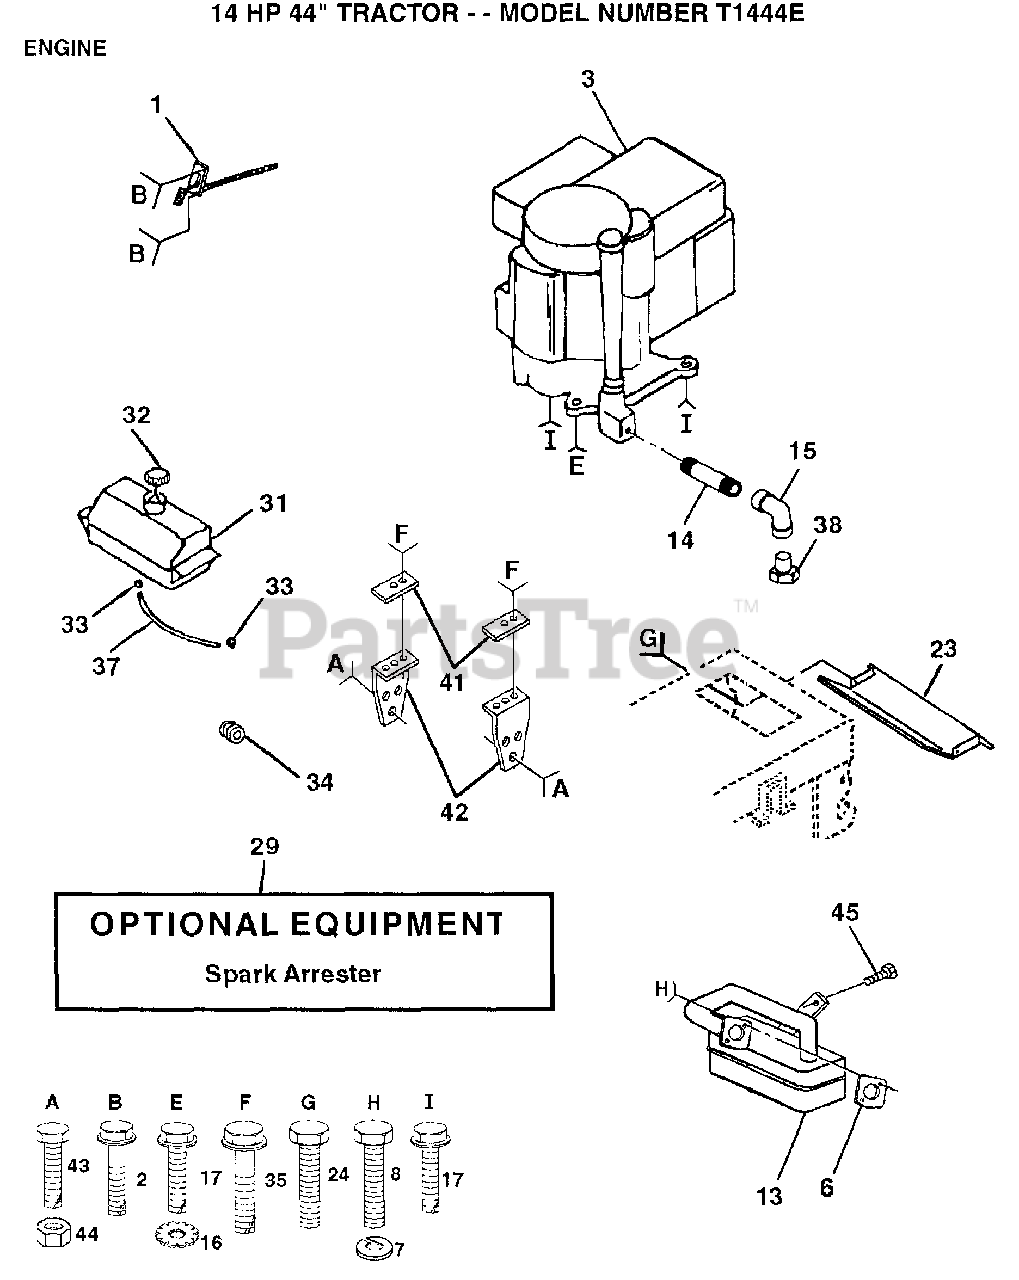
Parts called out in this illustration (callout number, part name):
1	THROTTLE CONTROL
2	SCREW LT
7	LOCKWASHER
8	SCREW
13	MUFFLER
14	PIPE NIPPLE
15	ELBOW
16	LOCKWASHER
17	SCREW
23	HEAT SHIELD
24	SCREW
31	TANK.FUEL.LT.
32	CAP ASM FUEL
33	HOSE CLAMP
35	SCREW
37	LINE FUEL
41	"CLAMP,FUEL TANK T"
42	BRKT FUEL TANK T
43	BOLT
44	NUT
45	SCREW HEX CRT
